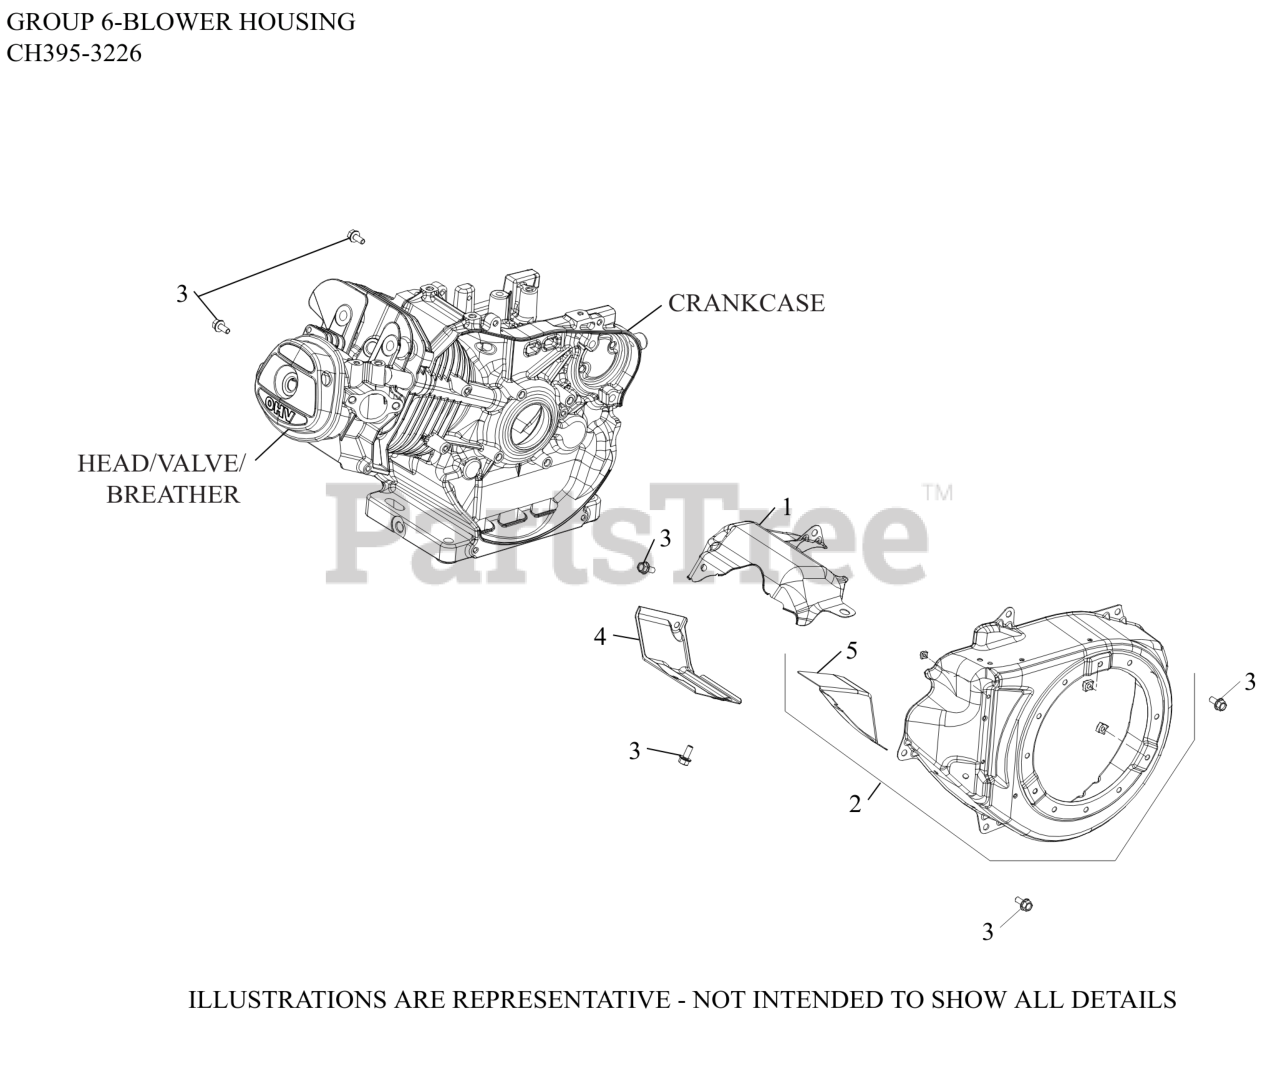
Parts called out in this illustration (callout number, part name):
1	SHIELD, UPPER HEAT
2	KIT, BLOWER HOUSING
3	SCREW, HEX FLANGE (M6)-USE 25 086 433-S
4	SHIELD, CYLINDER HEAD
5	SHIELD, OUTSIDE CYLINDER HEAD
